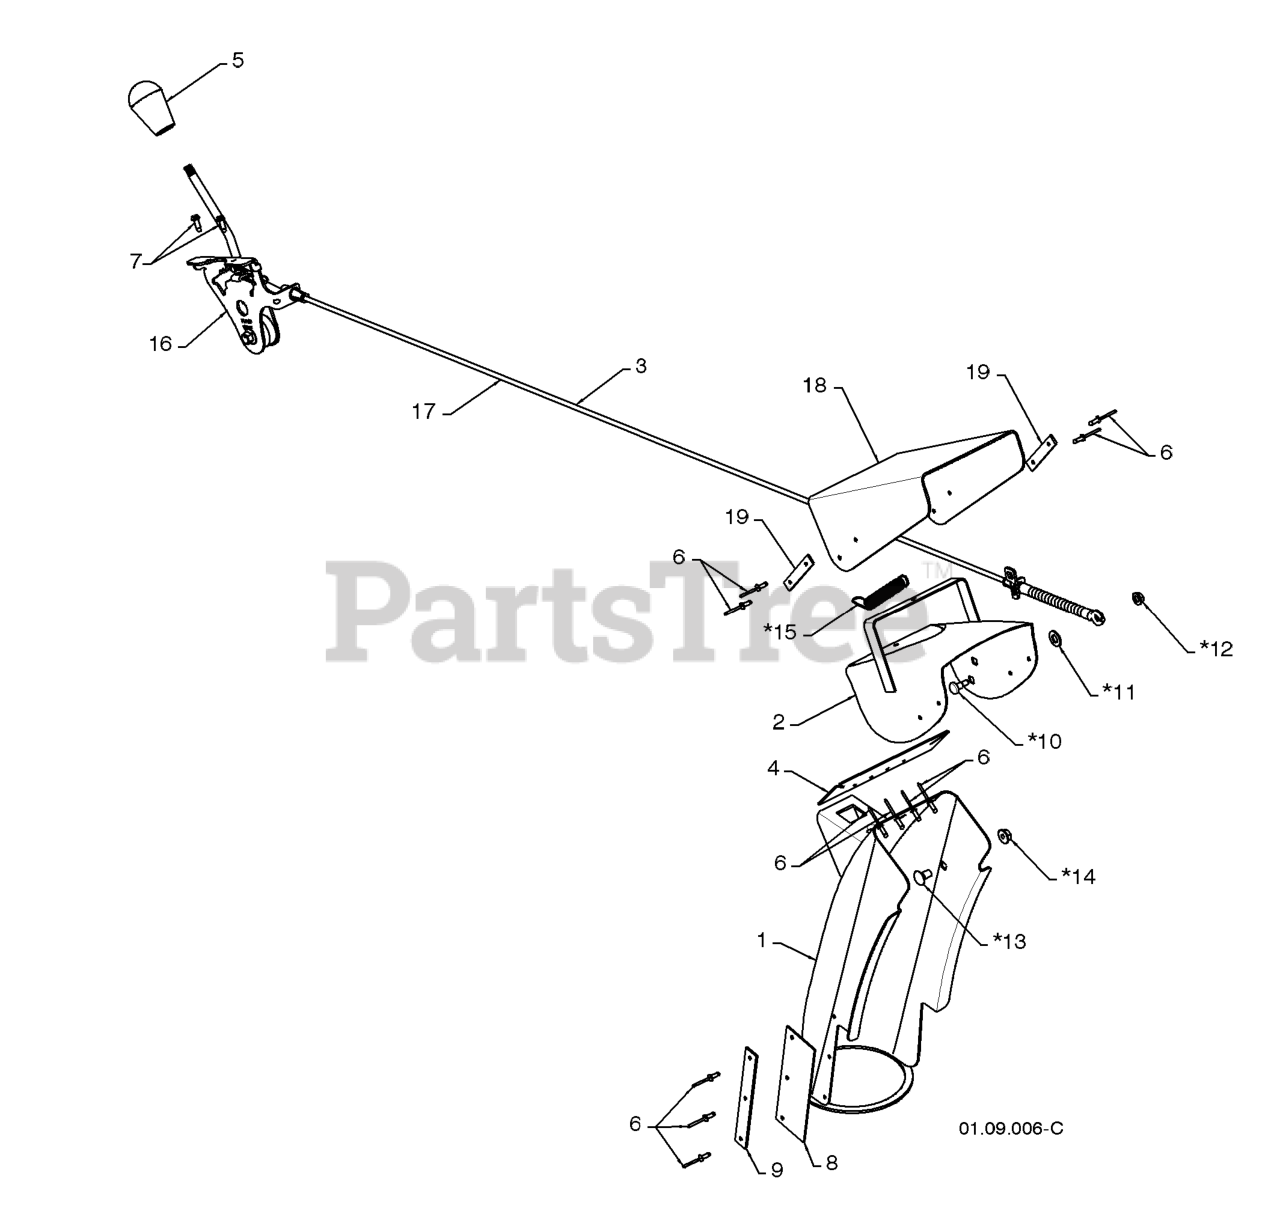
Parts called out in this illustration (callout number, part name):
1	CHUTE.WELDMENT
2	DEFLECTOR.WELDMENT.PNT.ORANGE
3	CONTROL.ASM.DEFLECTOR
4	SEAL.DEFLECTOR
5	KNOB LEVER, BLACK
6	RIVET BLIND
7	SCREW #10-24 X 5/8
8	SHIELD.SNOW.CHUTE
9	STRAP.SHEILD.RETAINER
10	BOLT, SHOULDER
11	WASHER, NYLON FRICTION
12	NUT.HEX.FLANGE.1/4
13	BOLT
14	NUT.LOCK.5/16-18
15	SPRING.DEFLECTOR.REM.CHUTE
16	RP CNTRL.HEAD.ASSEM.DEFLECTOR
17	SERVICE.CHUTE.DEF.CBL.GRY
18	SHIELD.DEFLECTOR.BLACK.SNOW
19	STRAP.DEFLECTOR.SHIELD
